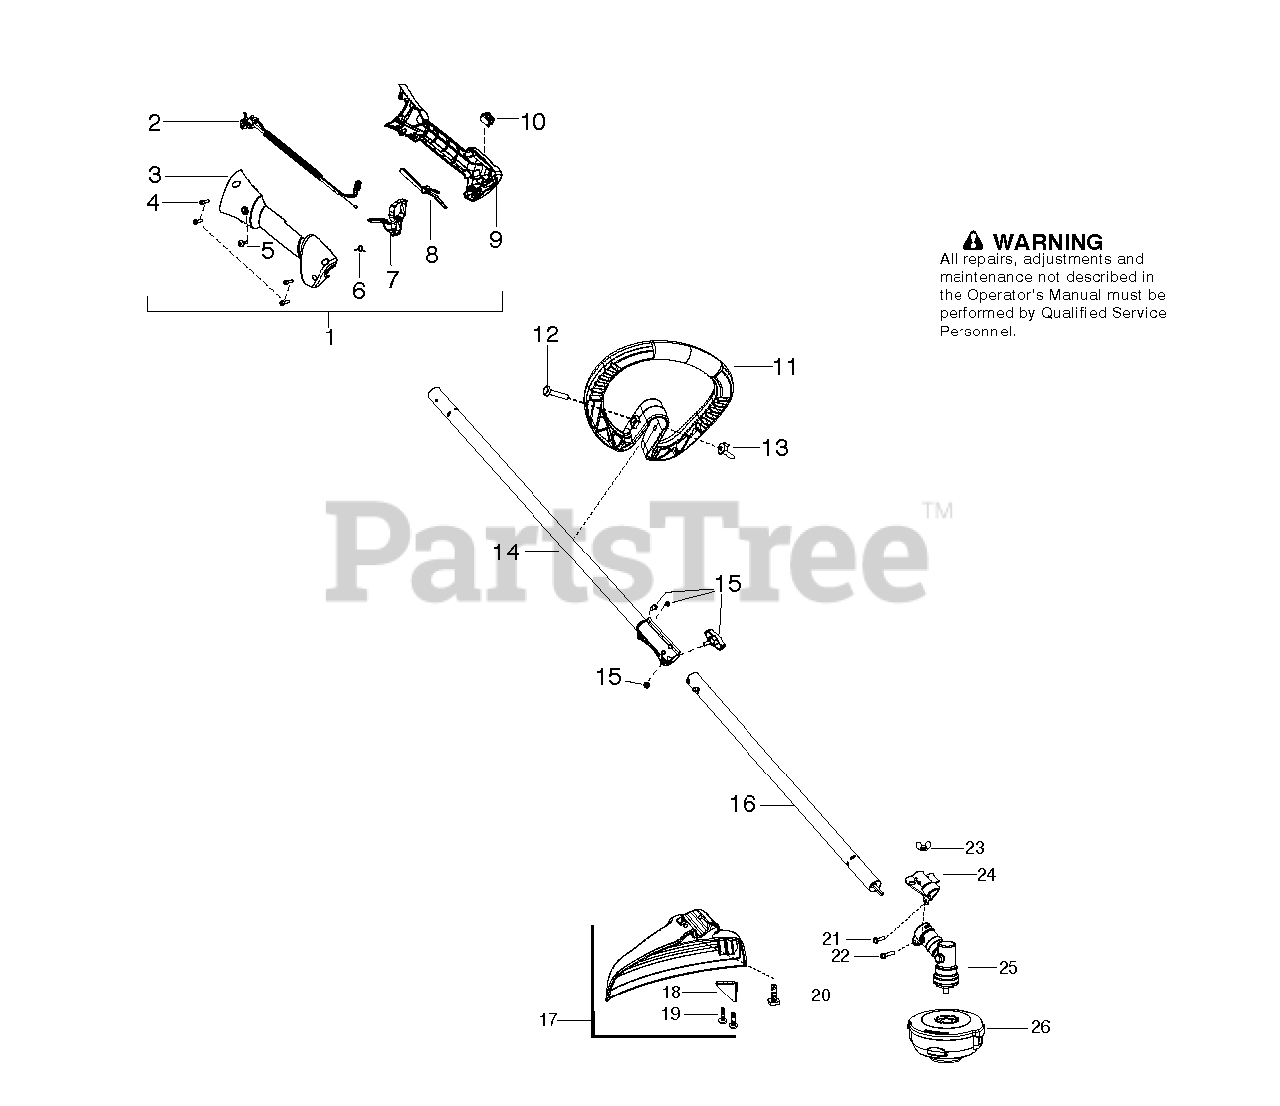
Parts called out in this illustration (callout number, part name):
2	ASSY CABLE/WIRE HARNESS
3	HANDLE HALF RIGHT
4	SCREW M4 X 1.75 PT 16MM
5	SCREW M4 X 1.75 PT 16MM
8	LOCKOUT TRIGGER
9	HANDLE HALF LEFT
10	STOP SWITCH
11	HANDLE ASSIST 1"
12	BOLT, TYPE 2
13	WINGNUT, TYPE 2
14	Drive Shaft Kit, Upper
15	ASSY COUPLER BLACK
16	Drive Shaft Kit, SST
17	Shield Kit
20	SCREW 8-16 X 9/16 (PLAS
21	SCREW - CARB. ADAPTOR
22	BOLT, TYPE 2
23	WINGNUT, TYPE 2
25	GEARBOX 1
26	ASSY TNG P25 PP28 COUNTERCLOCK
